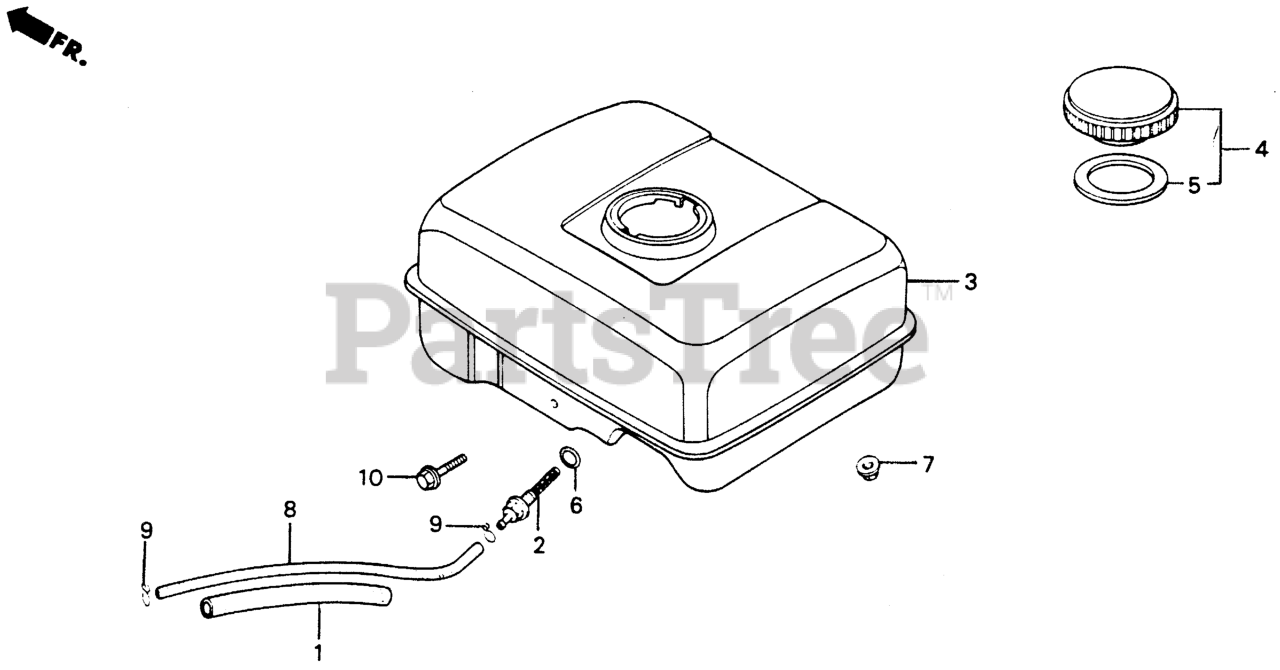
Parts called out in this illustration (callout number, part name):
1	RUBBER, SUPPORTER (107MM)
2	JOINT, FUEL TANK
3	TANK, FUEL *NH31* (MCKINLEY WHITE) Use up to Engine SN 3033315.
4	CAP, FUEL FILLER (BLACK) Use up to Engine SN 2115700.
4	CAP, FUEL FILLER (CHROME PLATED)
4	CAP COMP
4	CAP, FUEL FILLER
5	GASKET, FUEL FILLER CAP (39X58X3) (NOT AVAILABLE)
5	GASKET, FUEL FILLER CAP Use from Engine SN 1543258.
5	GASKET, FUEL FILLER CAP (39X58X3)
6	O-RING (14MM) (ARAI) Use up to Engine SN 2949254.
7	NUT, FLANGE (6MM)
8	BULK HOSE, FUEL (4.5X3000) (Honda Code 5137104). (4.5X140)
9	CLIP, TUBE (B8)
10	BOLT, FLANGE (6X25)
